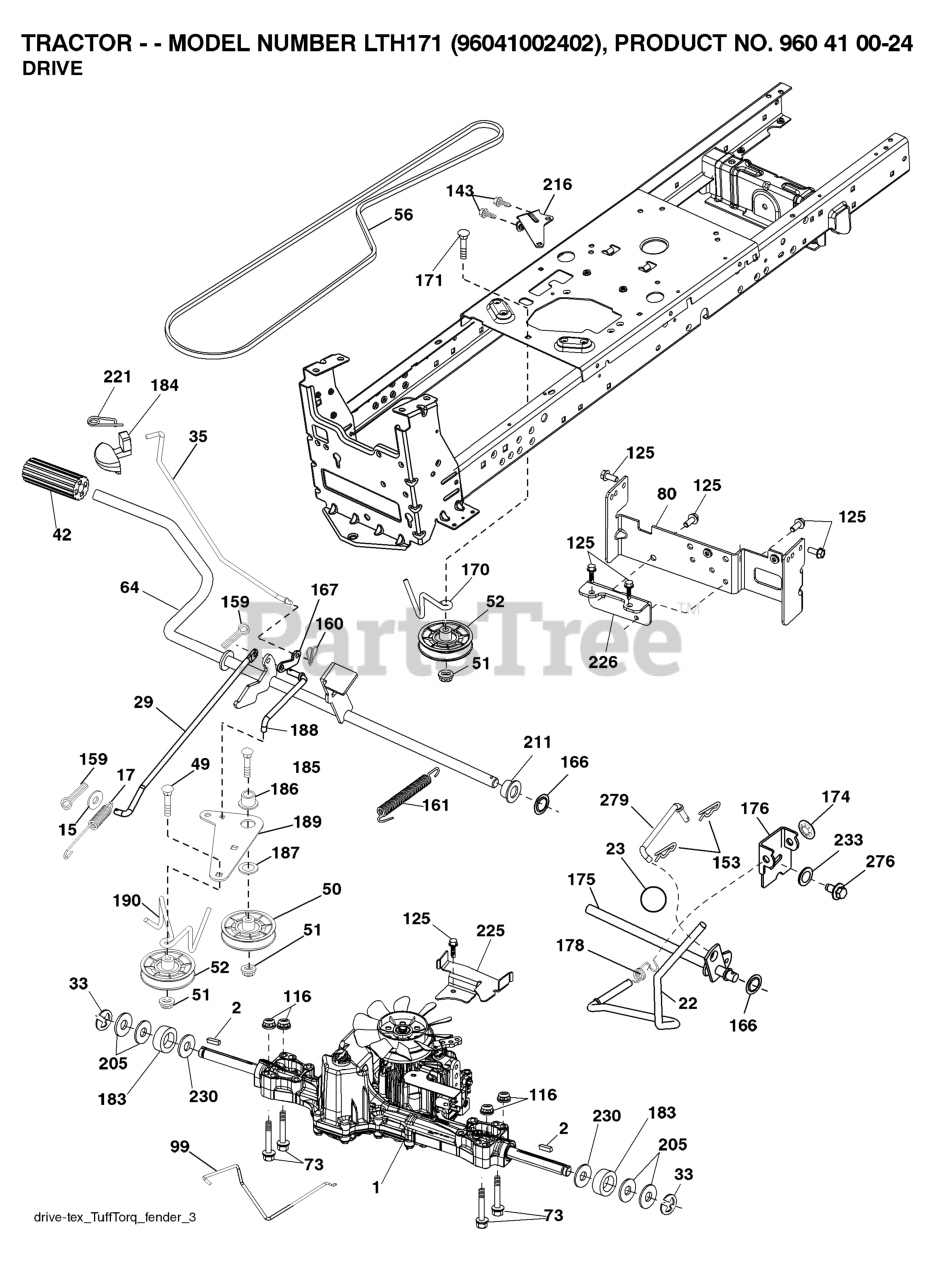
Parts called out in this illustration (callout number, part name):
2	SQUARE KEY
15	WASHER
17	SPRING.BRAKE.K46.GREEN
22	ROD.SHIFT.FENDER.TLT.2006
23	KNOB.DUCKHEAD.1/2
29	ROD.BRAKE.K46
35	ROD.CNTRL.PARK.PREDATOR.LT.TEX
42	PEDAL COVER T
50	IDLER.FLAT.910.OFFSET
51	NUT LOCK FLG 3/8-16 UNC
52	IDLER.V-GROOVE.910.OFFSET
56	V-BELT.MOWER.92.40.42/K46
64	SHAFT.ASM.PEDAL.BRAKE.
73	BOLT HEX 5/16-18 GR 5
80	STRAP TORQUE
99	ROD ASM BYPASS
116	NUT LOCK HEX FLANGE 5/16-18
125	SCREW
143	Screw 5/16-18 x 1/2 Hex, Self Tapping 5/16-18 x 1/2
153	RETAINER M
159	COTTER PIN
160	RETAINER CLIP
161	SPRING.RETURN.CLUTCH.2006
166	NUT.PUSH.625.2006
167	LATCH.BRAKE.SPRING
170	KEEPER.V-IDLER.CENTER.
174	NUT.PUSH.500.2006
175	SHAFT ASM SHIFT
176	ARM.CLEVIS.ROD.SHIFT
178	SPRING.SHIFT.GT2006
183	SPACER AXLE
184	HANDLE.PAKRING.BRAKE.
186	SPACER.RETAINER
187	WASHER 12/32X2X10GA
188	RP.LINK.CLUTCH.GROUND.DRIVE
189	BELLCRANK.GROUND.DRIVE.TEX.
190	KEEPER.BELLCRANK.DRIVE
211	BUSHING.SHAFT.BRAKE.HAND
216	BRACKET.PULLEY.IDLER.W/TEX
221	RETAINER.SPRING.CLIP.H
225	KEEPER.BELT.TRANSAXLE.K46
226	BRACKET.MOUNT.TORQUE.K46.TLT
230	WASHER.HARDENED
233	WASHER SERRATED
276	BOLT FIN HEX 7/16-14 X 1
279	LINK.SHIFT.T/A.K46.FEND.TX
